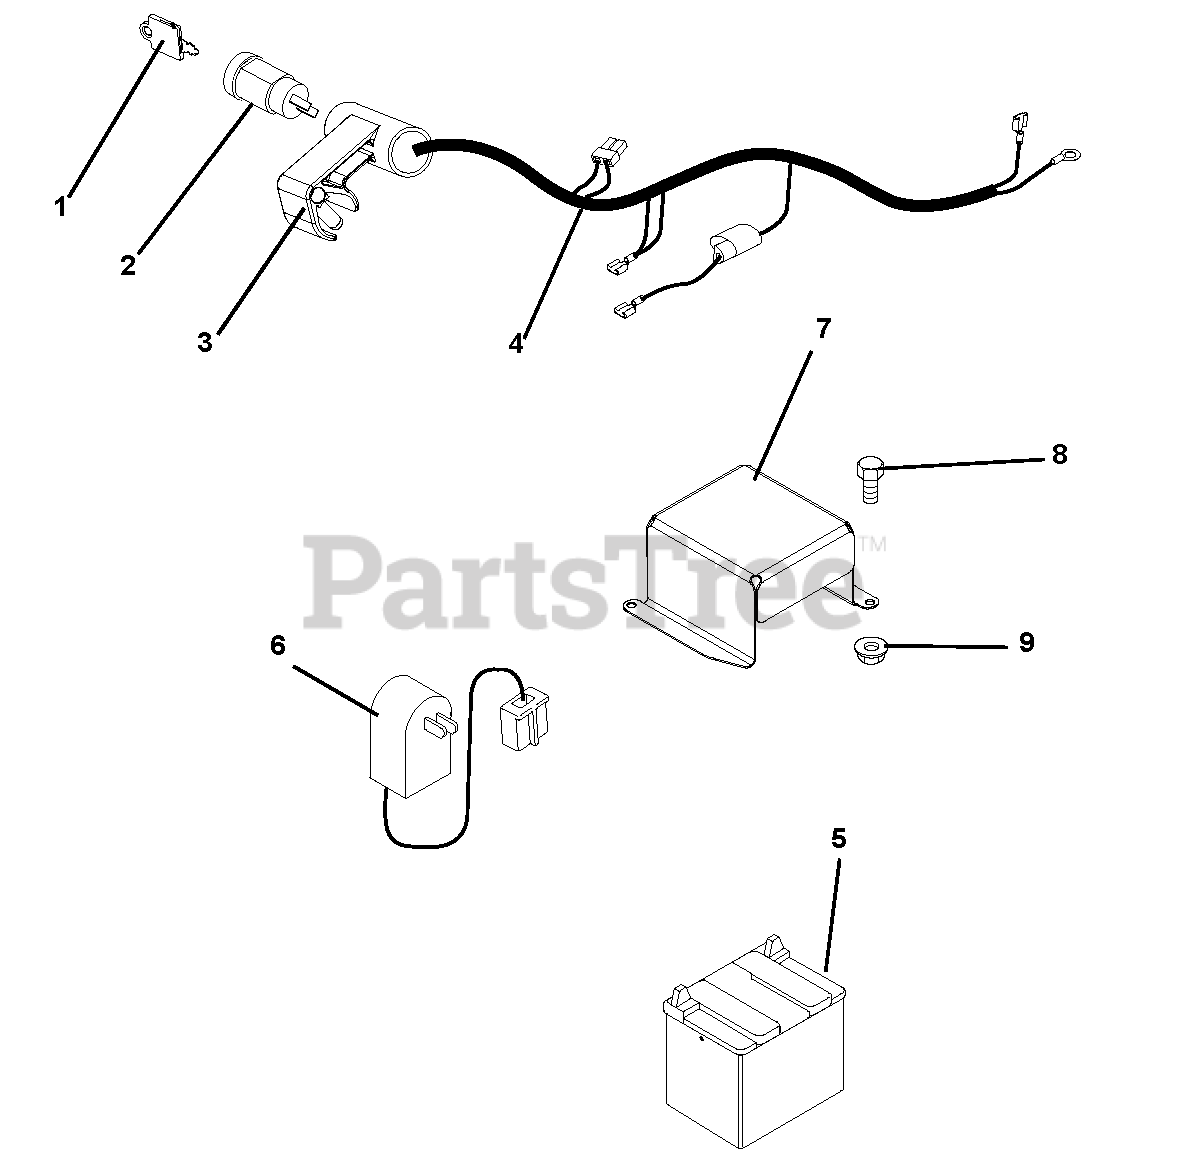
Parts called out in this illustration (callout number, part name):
2	Key, Switch
3	Housing, Switch
4	Harness, Wire
6	Battery, Charger
7	Cover, Battery
8	Bolt, Hex 8-32 x .5
9	Nut, Locking-Nylon 8-32
